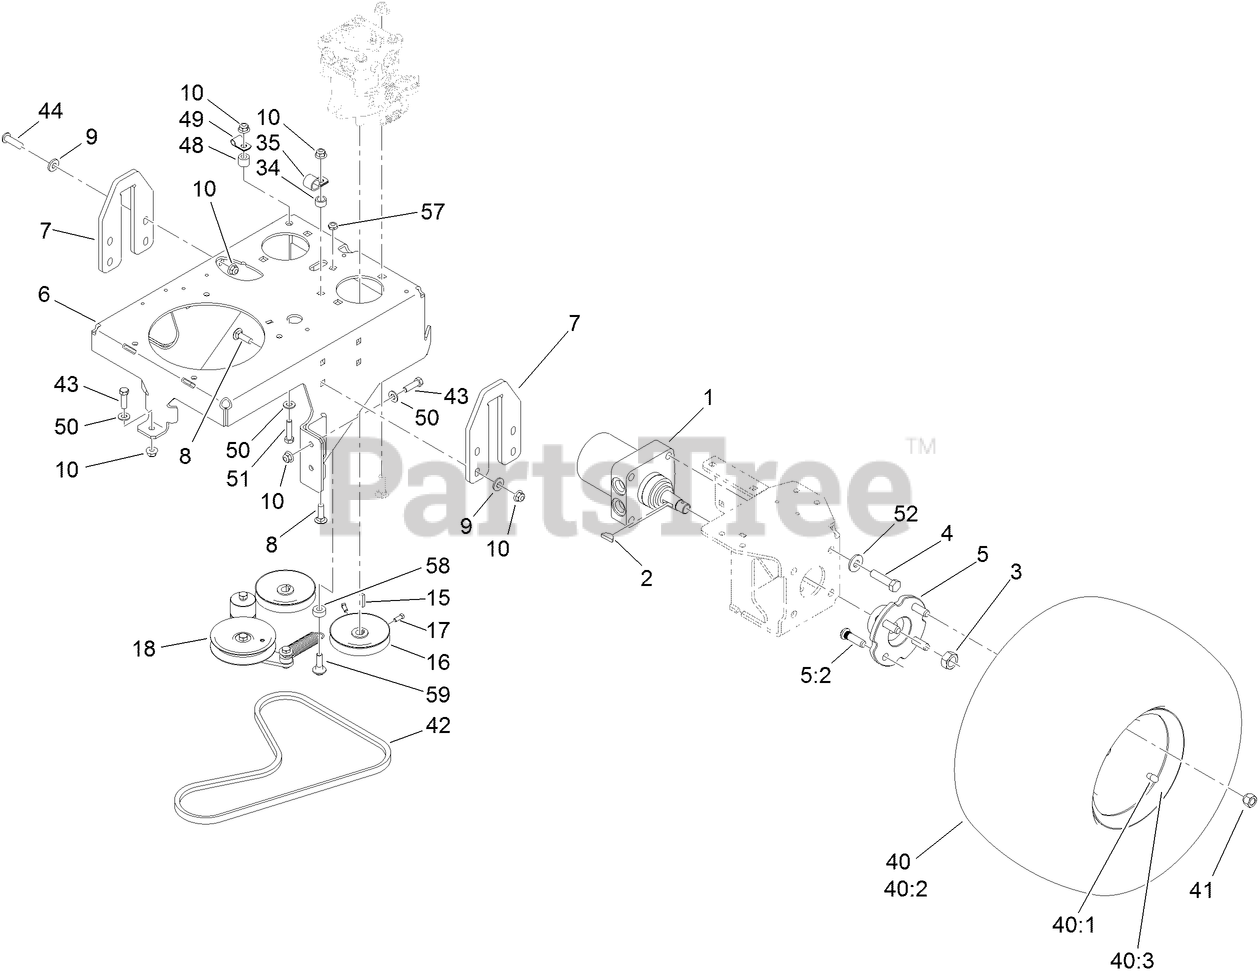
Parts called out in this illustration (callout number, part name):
1	HYD MOTOR ASM
2	KEY-WOODRUFF
3	NUT-MOTOR, WHEEL
4	SCREW-HH
5	WHEEL HUB ASM
5:2	STUD-TYPE, DRIVE
6	BASE-ENGINE
7	PLATE-LIFT
8	BOLT-CARR
9	WASHER-BELLEVILLE
10	NUT-HF, NI
16	PULLEY-PUMP
17	SCREW-SET
18	PUMP IDLER ASM
34	SPACER-WHEEL
35	CLIP-LOOM
40	WHEEL/TIRE ASM
40:1	RIM-8 INCH
40:3	STEM-VALVE
41	NUT-LUG
42	BELT-V, LOWER PTO
43	SCREW-HHF
44	SCREW-HSBH
48	SPACER
49	CLIP-TUBE
50	WASHER-FLAT
51	SCREW-HH
52	WASHER-SPRING
57	NUT-LOCK, NI
58	SPACER
59	SCREW-SHOULDER, HWH
